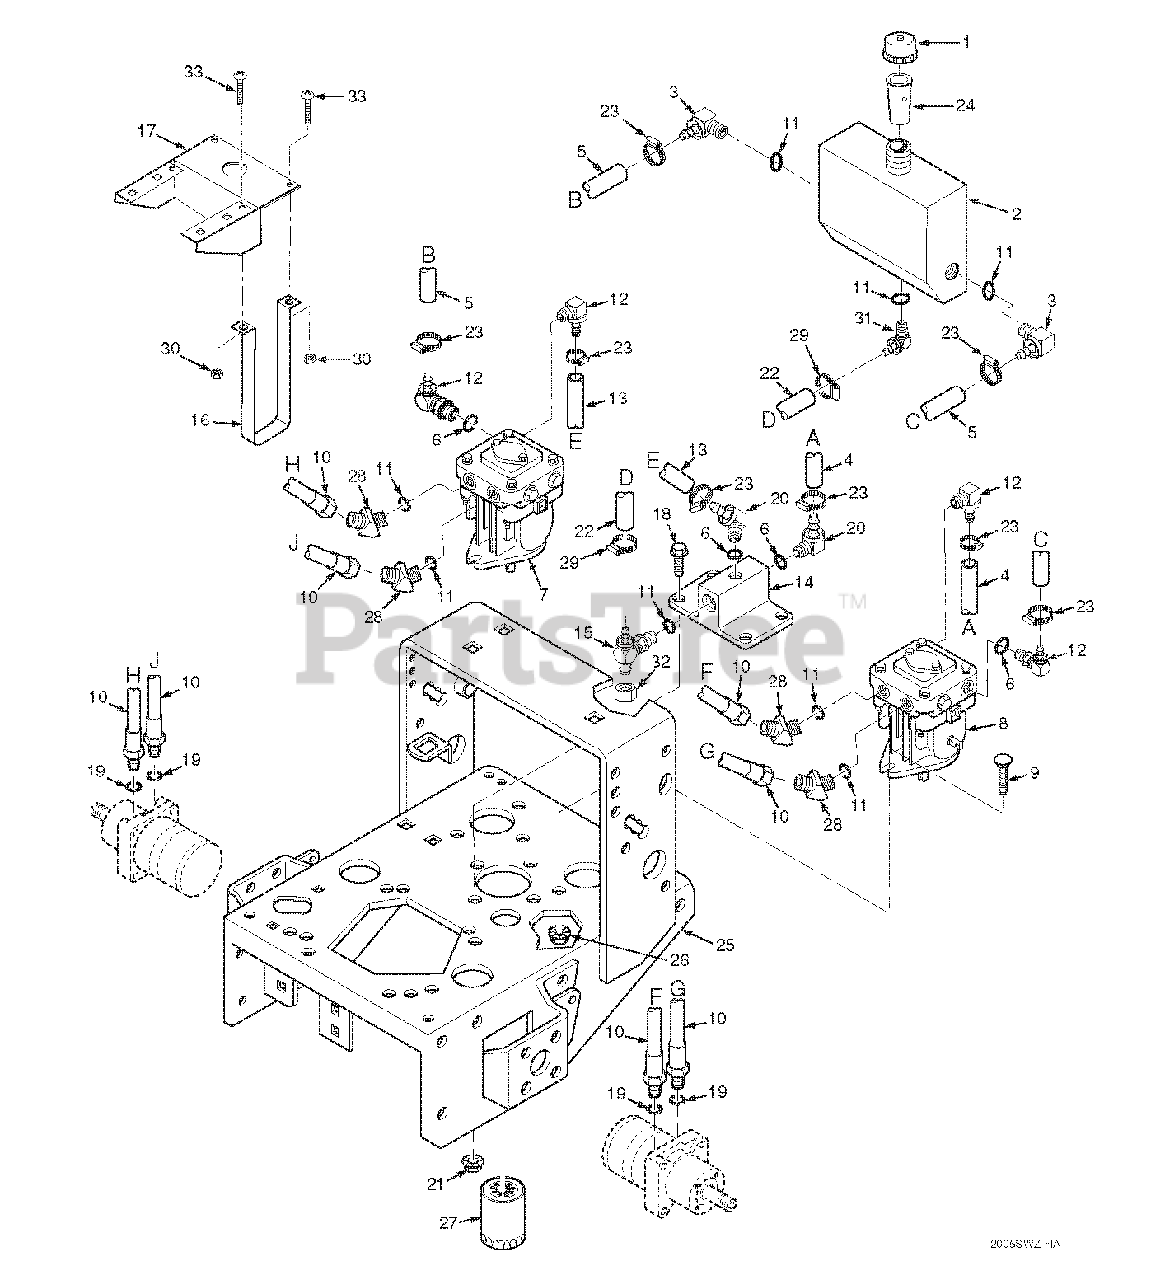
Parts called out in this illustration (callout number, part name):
1	Cap, Oil Reservoir
2	Oil Reservoir
3	Elbow, 9/16 O-Ring x 3/8" Hose
4	Hose, 3/8" ID - 10-1/4" Long
5	Hose, 3/8" ID - 7" Long
6	O-Ring
7	Pump
8	Pump
9	Bolt, Carriage, 3/8-16 x 1.25"
10	Hose, Pump to Wheel Motor
11	O-Ring
12	Elbow, 7/16-20 O-Ring x 3/8" Hose
13	Hose, 3/8" ID - 11" Long
14	Oil Filter Base
15	Tee, 3/8 O-Ring x JIC x 1/2" Hose
16	Strap, Hydraulic Tank
17	Bracket, Hydraulic Tank
18	Capscrew, 5/16-18 x .75" Serr. Flange
19	O-Ring
20	Elbow, 9/16 O-Ring x 3/8" Hose
21	Nut, 5/16-18 Serr. Flange
22	Hose, Formed 1/2" ID
23	Clamp, .69 max dia.
24	Tube, Filler Neck
25	Engine Deck (16" Wide) with Decals - Small Frame
26	Nut, 3/8-16 Serr. Flange
27	Oil Filter
28	Elbow, 45 Deg.-3/4-16 JIC Male x Male 3/4-16 O-Ring
29	Clamp, .87 max di.
30	Nut, 1/4-20
31	Elbow, 3/4-16 O-Ring x 1/2" Hose
32	Cap, 3/4-16
33	Screw, 1/4-20 x 2.0" Round Head Phillips
